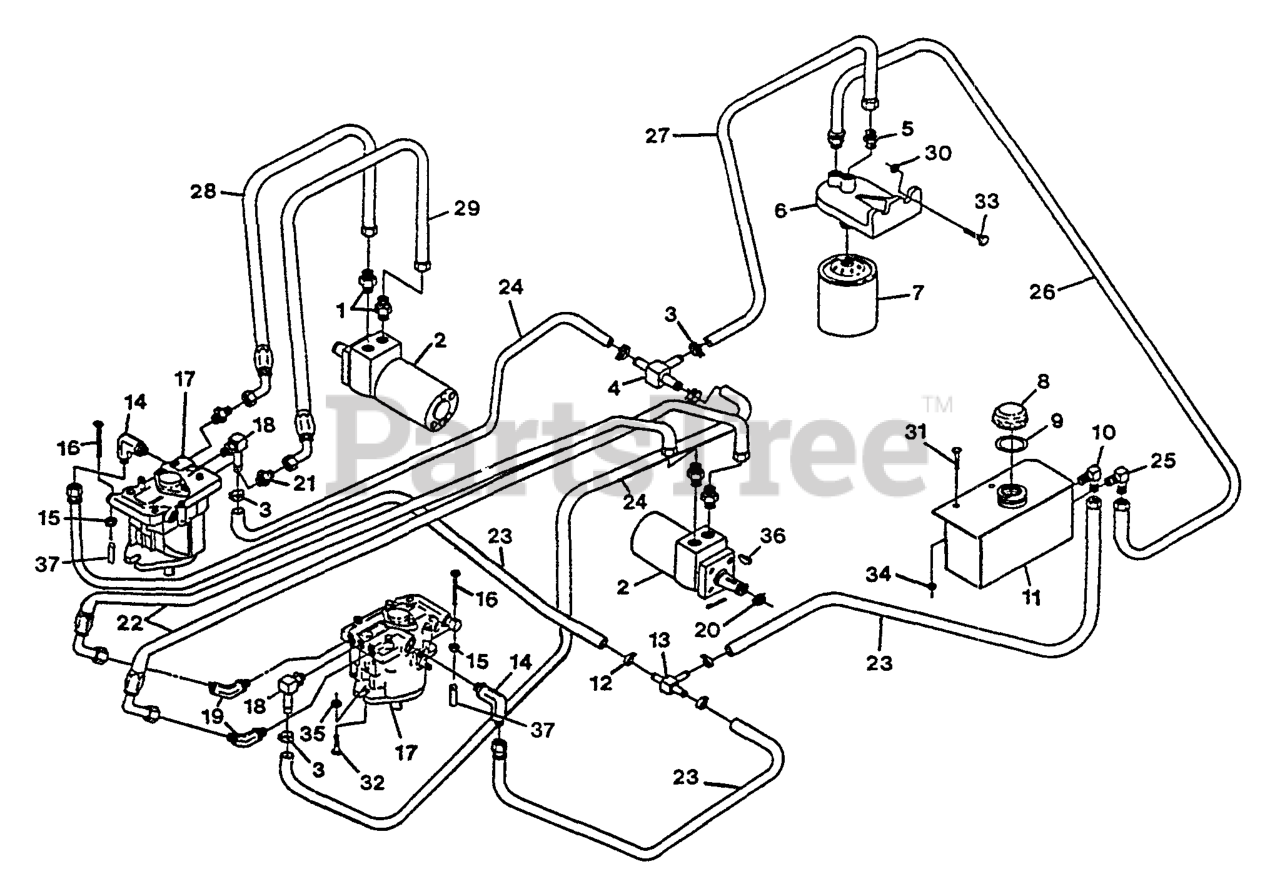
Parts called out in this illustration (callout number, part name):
1	FITTING-STRAIGHT
2	HYD MOTOR ASM
3	CLAMP-HOSE
4	FITTING-TEE, HOSE
5	FITTING-STRAIGHT
9	GASKET-CAP, TANK
10	FITTING-ELBOW
12	CLAMP-HOSE
13	FITTING-TEE, HOSE
14	FITTING-90 DEG
18	FITTING
19	FITTING-HYD, 45 DEG
21	FITTING-STRAIGHT
22	HOSE,HIGH PRESSURE
23	ASM,HOSE CASE DRAIN
24	HOSE,LO PRESSURE
25	FITTING-ELBOW
26	ASM,HOSE LO PRESSURE
27	ASM,HOSE CHARGE LINE
29	HOSE-PRESSURE, HIGH
36	KEY-WOODRUFF
37	GRIP-VALVE, DUMP
